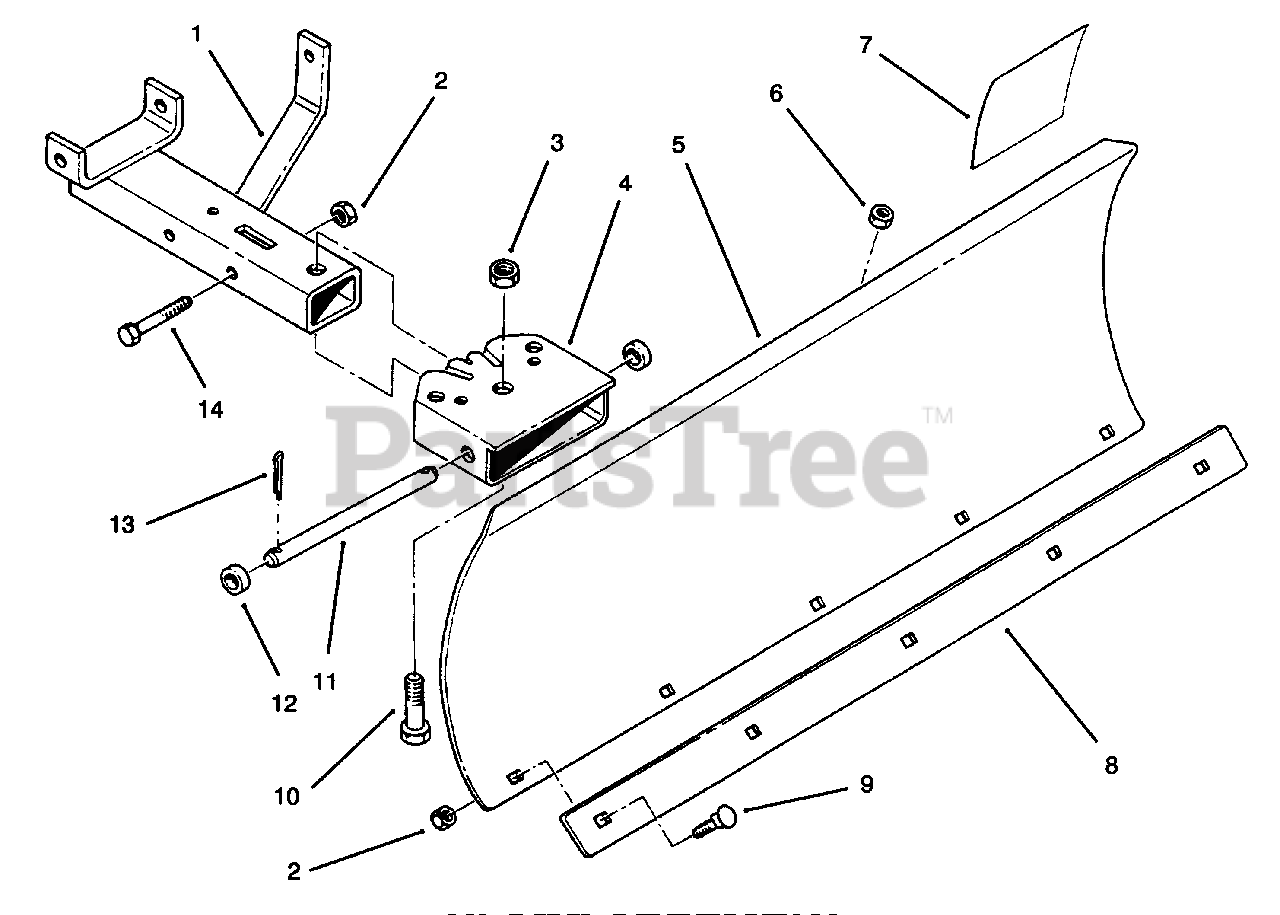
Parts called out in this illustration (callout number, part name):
1	Frame
2	Nut-Lock
3	Nut-Lock
4	Quadrant
5	Blade
6	Nut-Jam
7	Decal-Danger
8	Plate
9	Bolt-Carriage
10	Screw-Hex Hd. Cap
11	Rod-Lower Pivot
13	Pin-Cotter
14	Screw-Hex Hd. Cap
